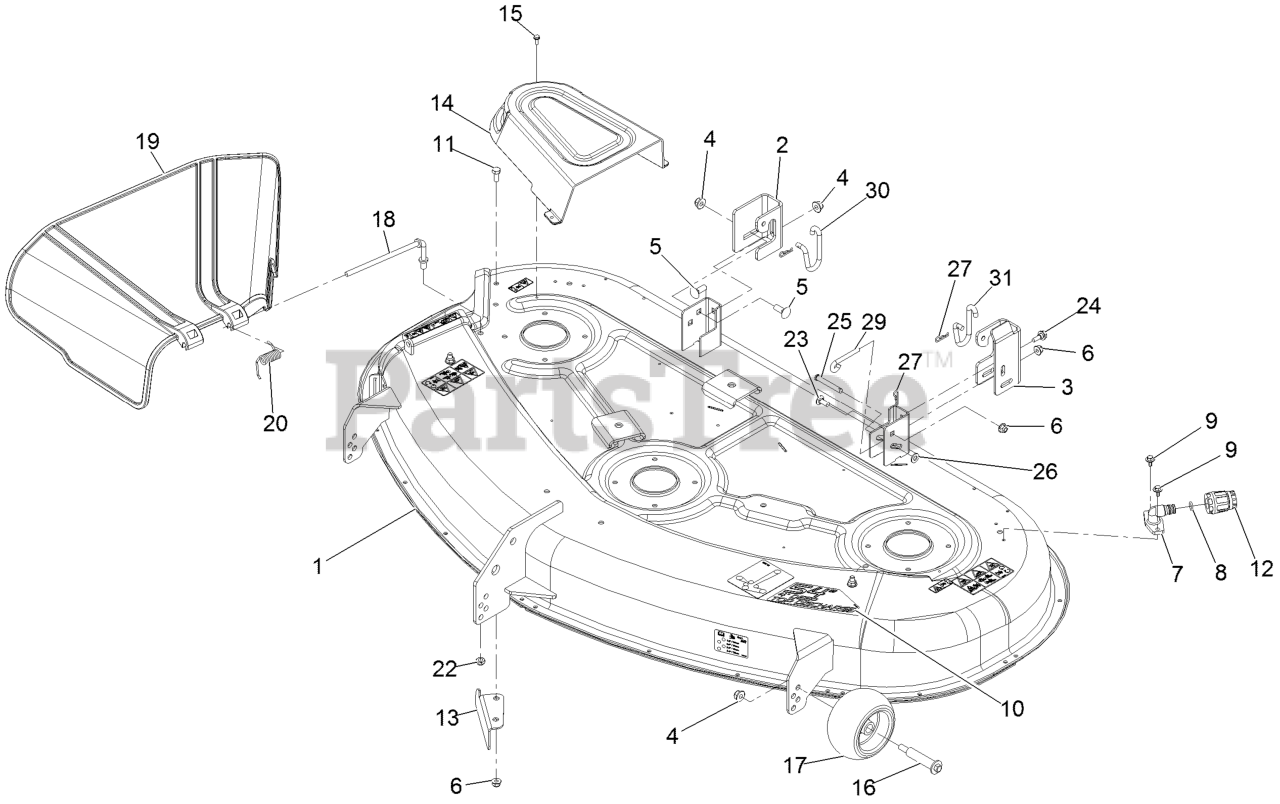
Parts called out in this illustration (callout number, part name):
1	54 INCH DECK ASM
2	BRACKET-HANGER, RH
3	BRACKET-HANGER, LH
4	NUT-HF, NI
5	BOLT-CARR
6	NUT-HF, NI
9	SCREW-HHFTF
10	DECAL-DECK
11	SCREW-HH
12	CONNECTOR-HOSE
13	BAFFLE-CUTOFF
14	COVER-BELT
15	SCREW-TAPTITE
16	BOLT-SHOULDER
17	ROLLER-SCALP, ANTI
18	ROD-PIVOT
19	DEFLECTOR
20	SPRING-TORSION
23	SCREW-CARR
24	SCREW-SHOULDER,HWH
25	PIN-CLEVIS
26	WASHER-PLAIN
27	PIN-COTTER
29	ROD-LEVEL, DECK
30	LINK-RETENTION, DECK (RH)
31	LINK-RETENTION, DECK (LH)
